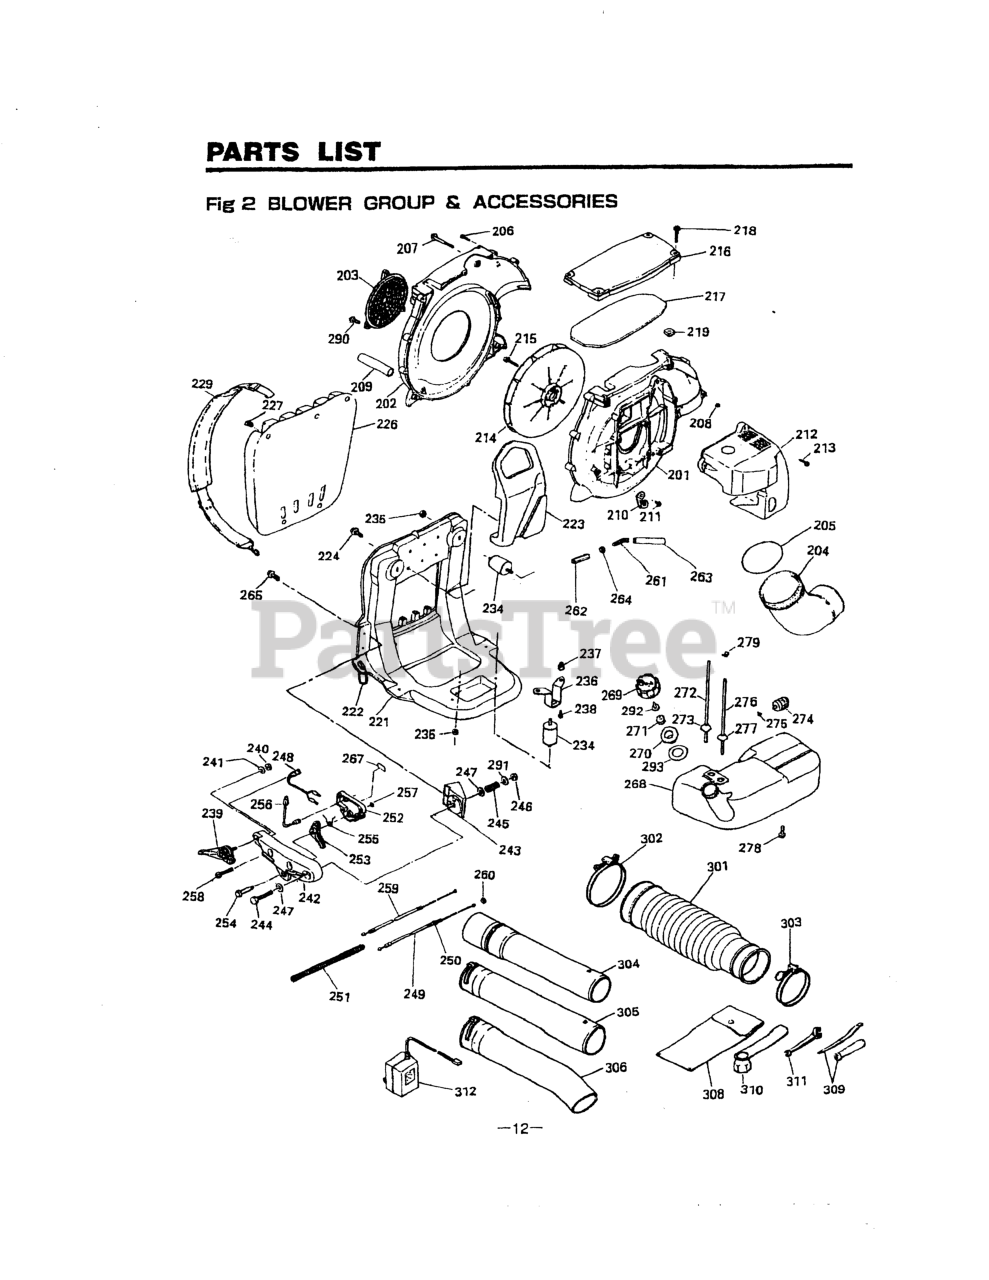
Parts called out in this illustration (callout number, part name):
201	CASE, VOLUTE
202	COVER, VOLUTE
203	NET, GUARD (RPLS-12222)
205	O-RING
206	SCREW
207	SCREW (RPLS 3490-11171)
210	BRACKET
211	SCREW (RPLS -16120)
212	COVER, ENGINE (RPLS-11210)
213	SCREW (RPLS -11221)
214	FAN (REPLACES 3490-12110)
216	COVER (RPLS -13111)
217	COVER, PACKING
218	SCREW
219	NUT
221	FRAME COMPLETE
222	RING (USE -21121)
223	HANGER (RPLS -21210)
226	PAD (RPLS -21310)
227	CLIP (RPLS 3490-21320)
235	NUT, M6 X 5
236	BRACKET (RPLS -22510)
237	WASHER
238	BOLT, M5 x 20
239	LEVER, THROTTLE
240	NUT (B)
241	WASHER, M5x.8(RPLS 01624-20508
243	BRACKET
244	BOLT
245	SPRING
246	NUT, M6 X 5
247	WASHER, PLANE(USE 01640-20816)
248	SWITCH, STOP
249	CABLE COMP,THROTTLE EB441
250	NUT, M6 X 5
251	TUBE (USE 5548-73310)
253	LEVER
256	SWITCH ASSEMBLY
257	RING, SNAP, M4
258	SCREW
259	CABLE COMP, CHOKE
260	NUT, M6 X 5
261	PIPE (RPLS -83210)
263	TUBE (RPLS -83310)
264	NUT, M6 X 5
265	BOLT
267	LABEL, ARM
269	CAP ASSY (RPLS -23202)
272	PIPE (RPLS 3490-23410)
273	GROMMET
274	FILTER ASSY
275	CLIP (REPLACES 2841-31280)
276	PIPE ASSEMBLY
277	GROMMET
278	SCREW (RPLS -23610)
279	CLIP
290	SCREW (RPLS -16120)
291	WASHER
293	PACKING (RPLS -85321)
301	HOSE, FLEXIBLE
302	2756-51510 (RPLS. 07280-09832)
304	JOINT, SWIVEL
305	PIPE, EXTENSION
306	PIPE, BENT
308	TOOL SET (RPLS-91000)
309	SCREWDRIVER
311	SPANNER, 8 X 10 (RPLS 2540- )
312	CHARGER, FOR 120V AC
